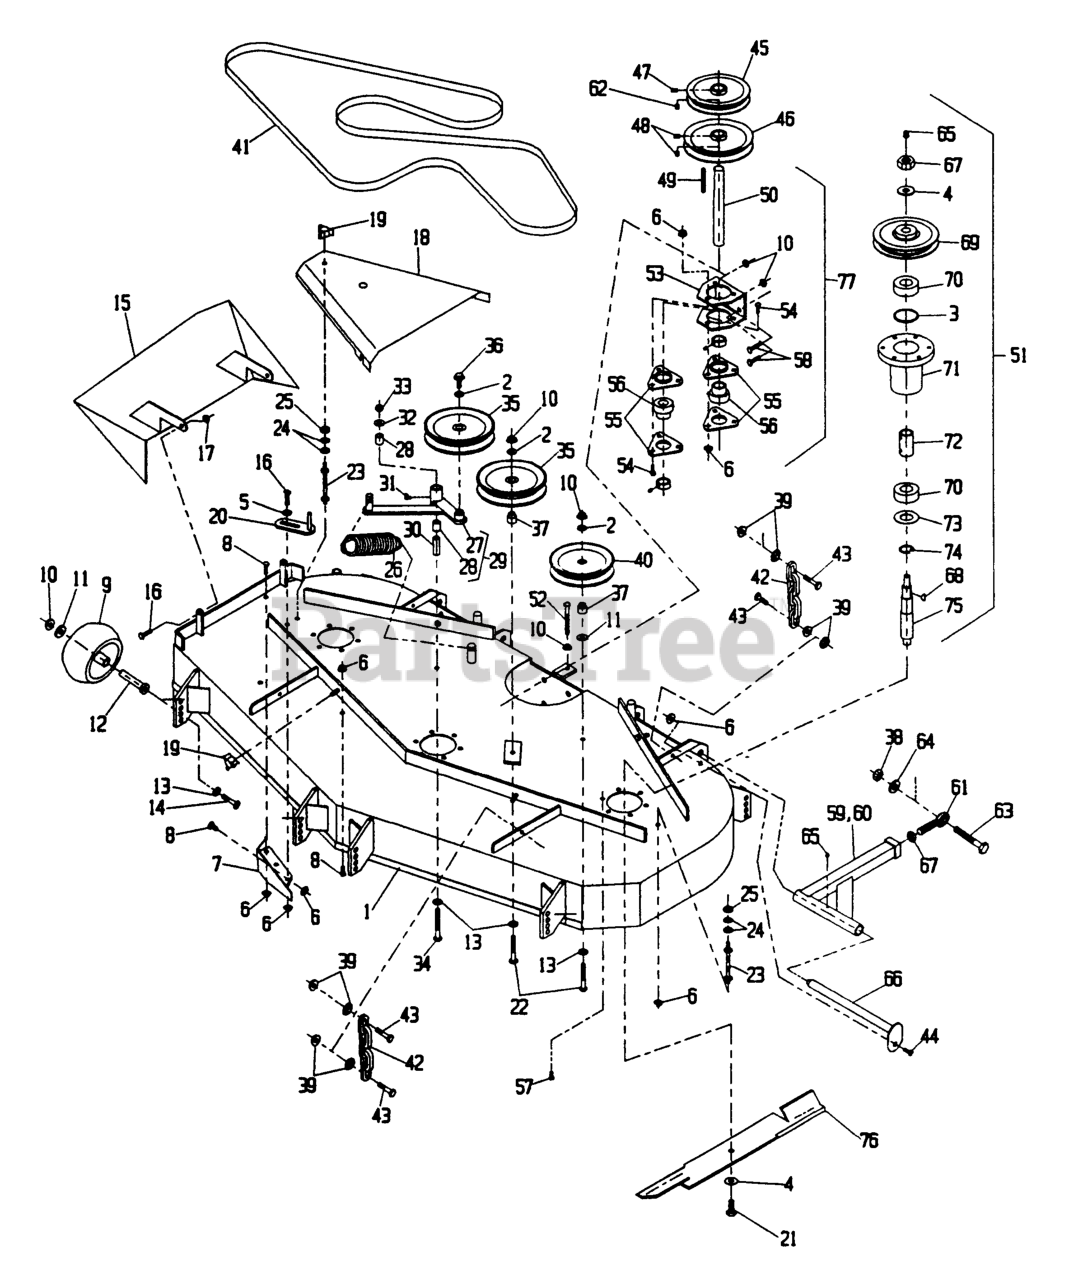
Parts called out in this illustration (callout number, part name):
4	WASHER-SPRING
5	WASHER-SPRING
7	WLD,BAFFLE DISCHARGE
9	ROLLER-SCALP, ANTI
12	BUSHING-ROLLER
15	WLD,CHUTE DISCHARGE
18	SHIELD,BELT 52
19	KNOB-3 PRONG
20	GUIDE-BELT
23	STUD-SHIELD, BELT (SHORT)
28	SLEEVE-BEARING
30	BUSHING
37	BUSHING-IDLER
40	PULLEY-IDLER
41	BELT,BLADE DRIVE 52
42	CHAIN-LIFT, DECK
43	SCREW-CAP, HH
46	SHEAVE,SPLIT STEEL
48	SCREW-SET
49	KEY,MACH 1/4X1/4X2-5/8
50	JACKSHAFT,DECK DRIVE
51	CUTTER HOUSING ASSY
53	BRACKET,JACKSHAFT
55	HOUSING-FLANGE
56	BEARING,W/COLLAR
57	SCRW,TPTTE HH
61	BALLJOINT-SPHERICAL
62	SCREW-SET
66	PIN-STRUT
69	PULLEY-CAST IRON
70	BEARING,HD SPINDLE
71	HOUSING,BEARING
72	SPACER,BEARING
73	SEAL,MECHANICAL DUST
74	RING,SNAP WLDS N5000-244
75	SPINDLE - BLADE
77	DK DR. BRG. ASSY
